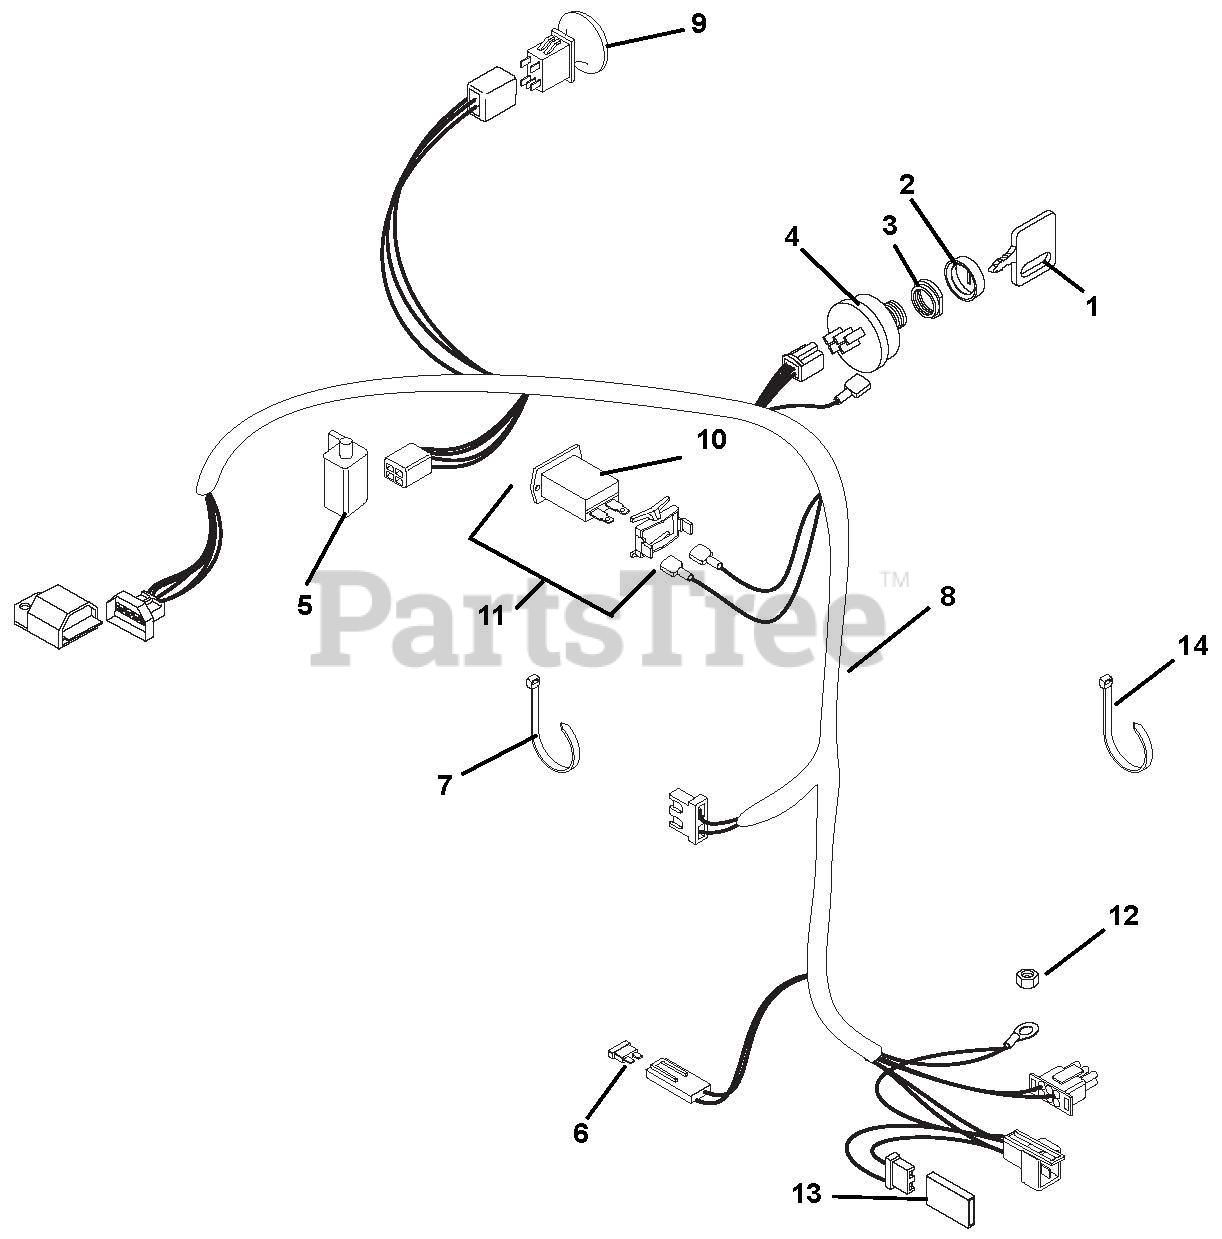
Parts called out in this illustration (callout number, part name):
1	Key- with Cap
2	Cap, Ignition Switch
3	Nut, Panel .562-24
4	Key Switch
5	Switch- Interlock
6	Fuse-25 AMP
7	Tie Wrap-Black
8	Wire Harness, Pro Gear
9	Switch, PTO N.M.I.R.
10	Hour Meter-Quartz
11	Kit, Hour Meter
12	Nut-Locking-Top-Flange .31-18
13	Diode, Connector Shell
14	Tie Wrap
